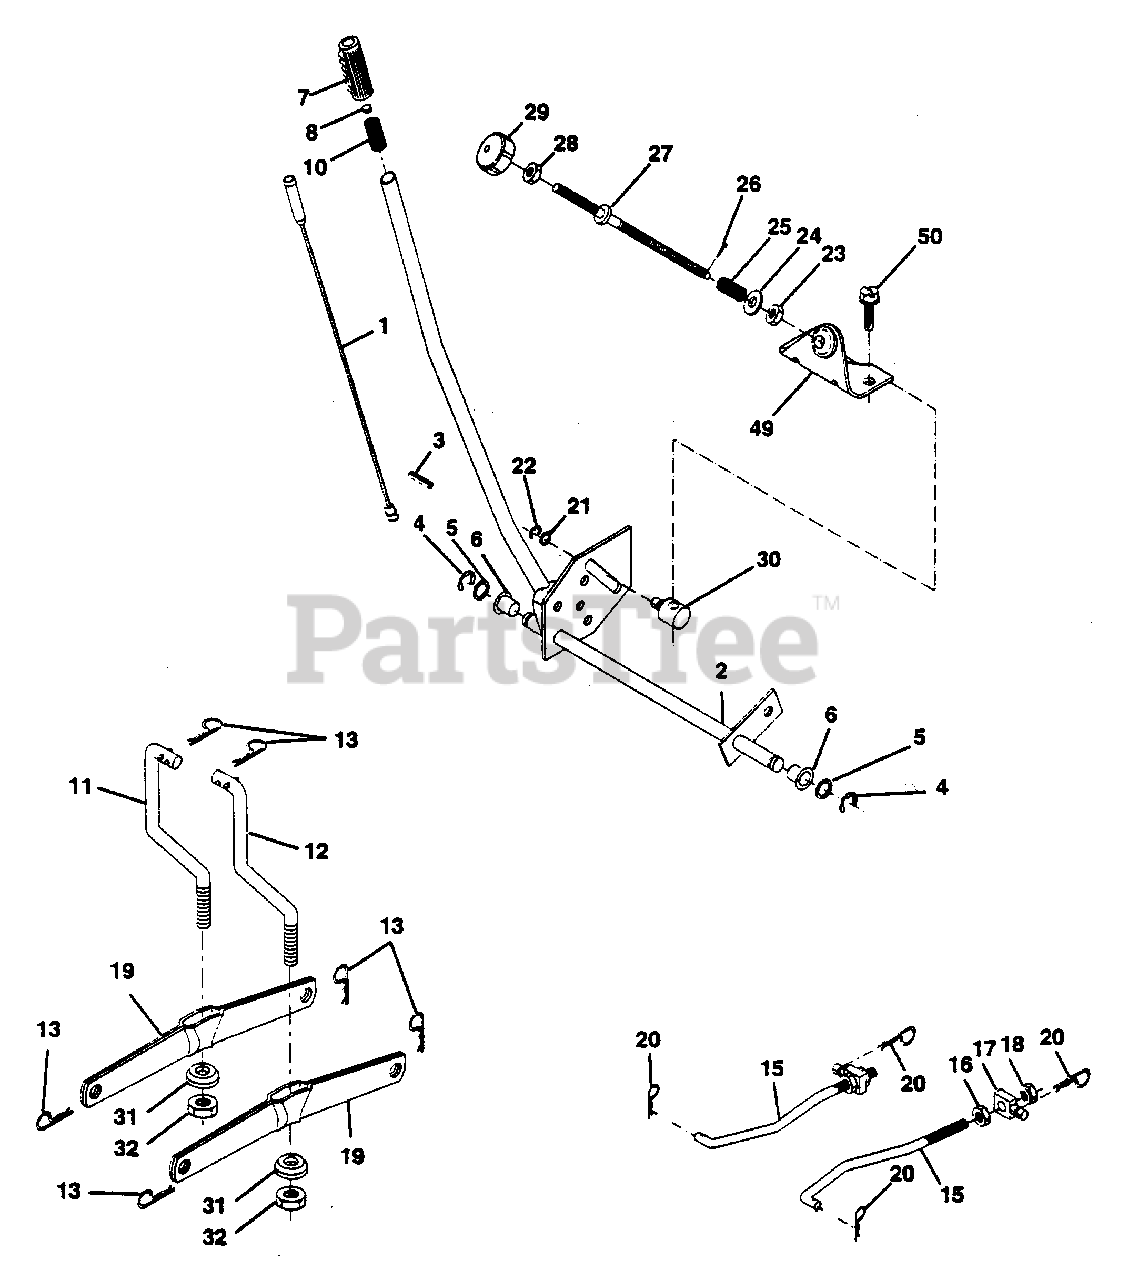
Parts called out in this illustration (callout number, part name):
1	Wire Asm Inner w/plunger (AYP part number)
2	Shaft Asm Lift LH Inf Hgt P/L (AYP part number)
3	Pin Groove (AYP part number)
4	E Ring #5133-62 (AYP part number)
5	Washer PLTD 21/32 X 1 X 21ga (AYP part number)
6	Bearing Nylon Blk 629 Id (AYP part number)
7	Grip Handle Bicycle Matte Blk (AYP part number)
8	Button Plunger Black (AYP part number)
10	Spring Cprsn 3 750 Oiled
11	Link Lift LH (AYP part number)
12	Link Lift RH
13	Retainer Spring (AYP part number)
15	Link Front (AYP part number)
16	Nut Jam Hex 1/2-13 Unc (AYP part number)
17	Trunnion Blk Zinc (AYP part number)
18	Nut Lock W/wsh 1/2-13unc (AYP part number)
19	Arm Suspension Rear (AYP part number)
20	Retainer Spring (AYP part number)
21	Washer 15/32 X 3/4 X 16ga (AYP part number)
22	Ring Klip (AYP part number)
23	Nut Special (AYP part number)
24	Washer 13/32 x 5/8 x 16 ga (AYP part number)
25	Spring 2-1/8 (AYP part number)
26	Pin Cotter 3/32 x 1/2 (AYP part number)
27	Rod Adj Lift
28	Nut Hex Jam 3/8-16 Unc (AYP part number)
29	Knob Inf 3/8-16 UNC (AYP part number)
30	Trunnion Dp Stop
31	Bearing Pivot Lift Spherical (AYP part number)
32	Nut Lock 3/8-24 w/nylon Insert (AYP part number)
49	Bracket Stop Inf Hgt (AYP part number)
50	Screw Thdrol 3/8-16 x 1/2 (AYP part number)
